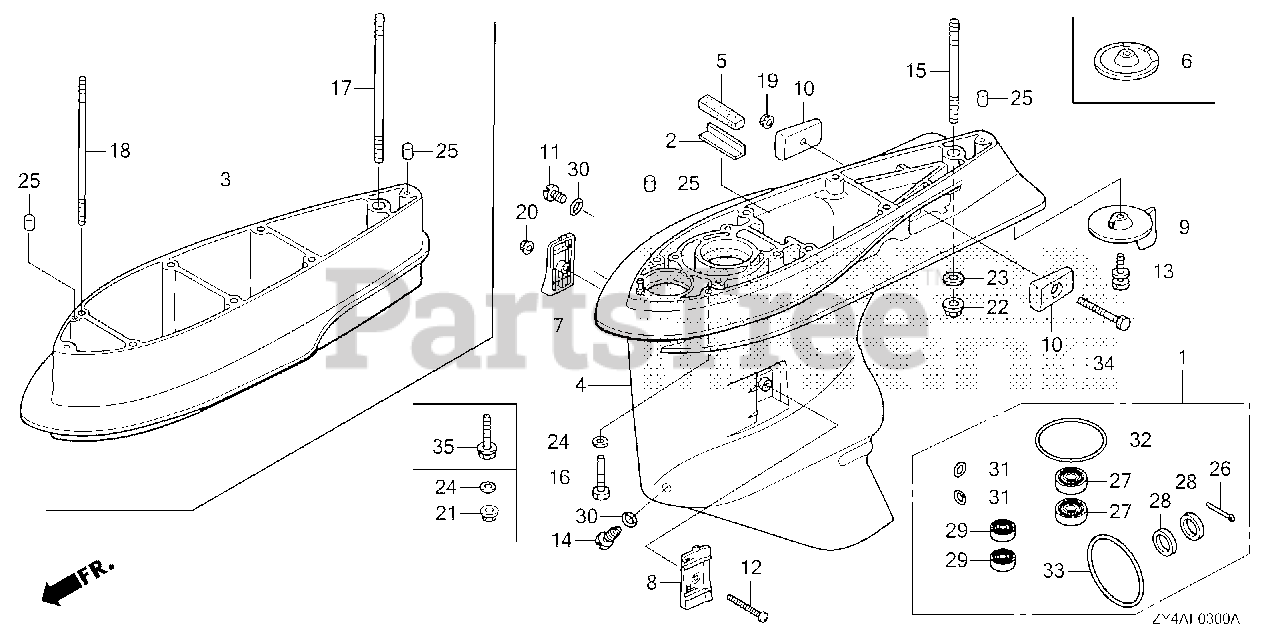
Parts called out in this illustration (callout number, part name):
2	PLATE, RUBBER SETTING
4	CASE, GEAR *NHB14M* (AQUA MARINE SILVER METALLIC)
4	CASE, GEAR *NH565* (GRAND PRIX WHITE)
5	GROMMET, GEAR CASE
6	COVER, GEAR CASE *NHB14M* (AQUA MARINE SILVER METALLIC)
6	COVER, GEAR CASE *NH565* (GRAND PRIX WHITE)
7	SCREEN, R. WATER
8	SCREEN, L. WATER
10	METAL, ANODE
11	BOLT, OIL CHECK
12	SCREW, FLAT (5X55)
13	BOLT-WASHER (10X32)
14	BOLT, DRAIN PLUG
15	BOLT, STUD (12X40)
19	NUT, SELF-LOCK (6MM)
20	NUT, SELF-LOCK (5MM)
22	NUT, SELF-LOCK (12MM)
23	WASHER, PLAIN (12MM)
25	PIN, DOWEL (6X10)
30	O-RING (6.9X1.45)
34	BOLT, HEX. (6X55)
35	BOLT-WASHER (10X47)
